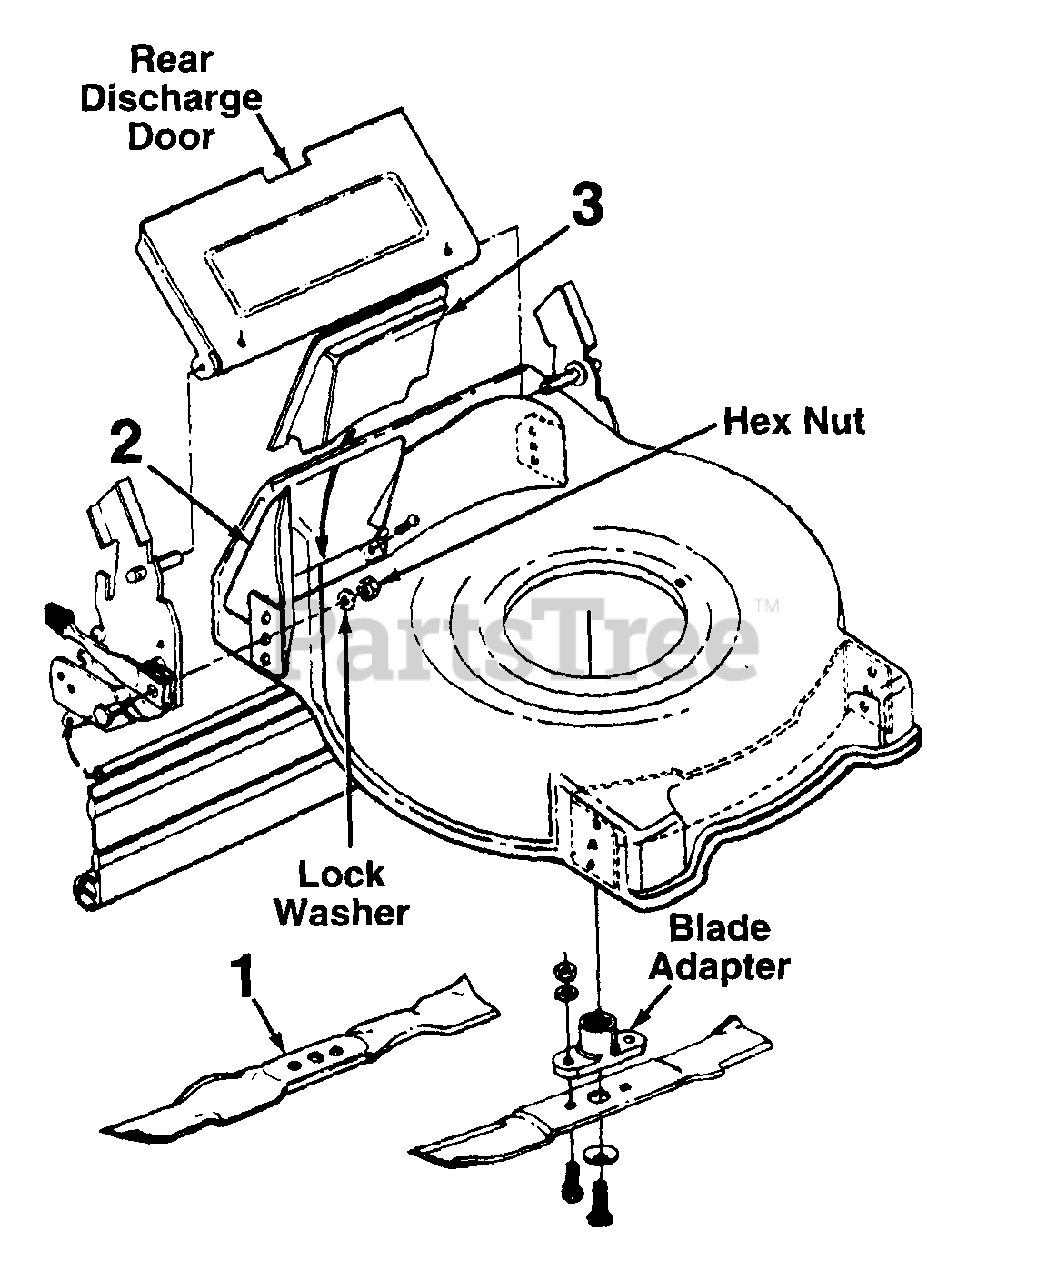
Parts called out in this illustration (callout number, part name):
1	21" Mulching Blade (082)
1	19" Mulching Blade (099)
2	Mulching Baffle - R.R.
3	Mulching Baffle Plug
